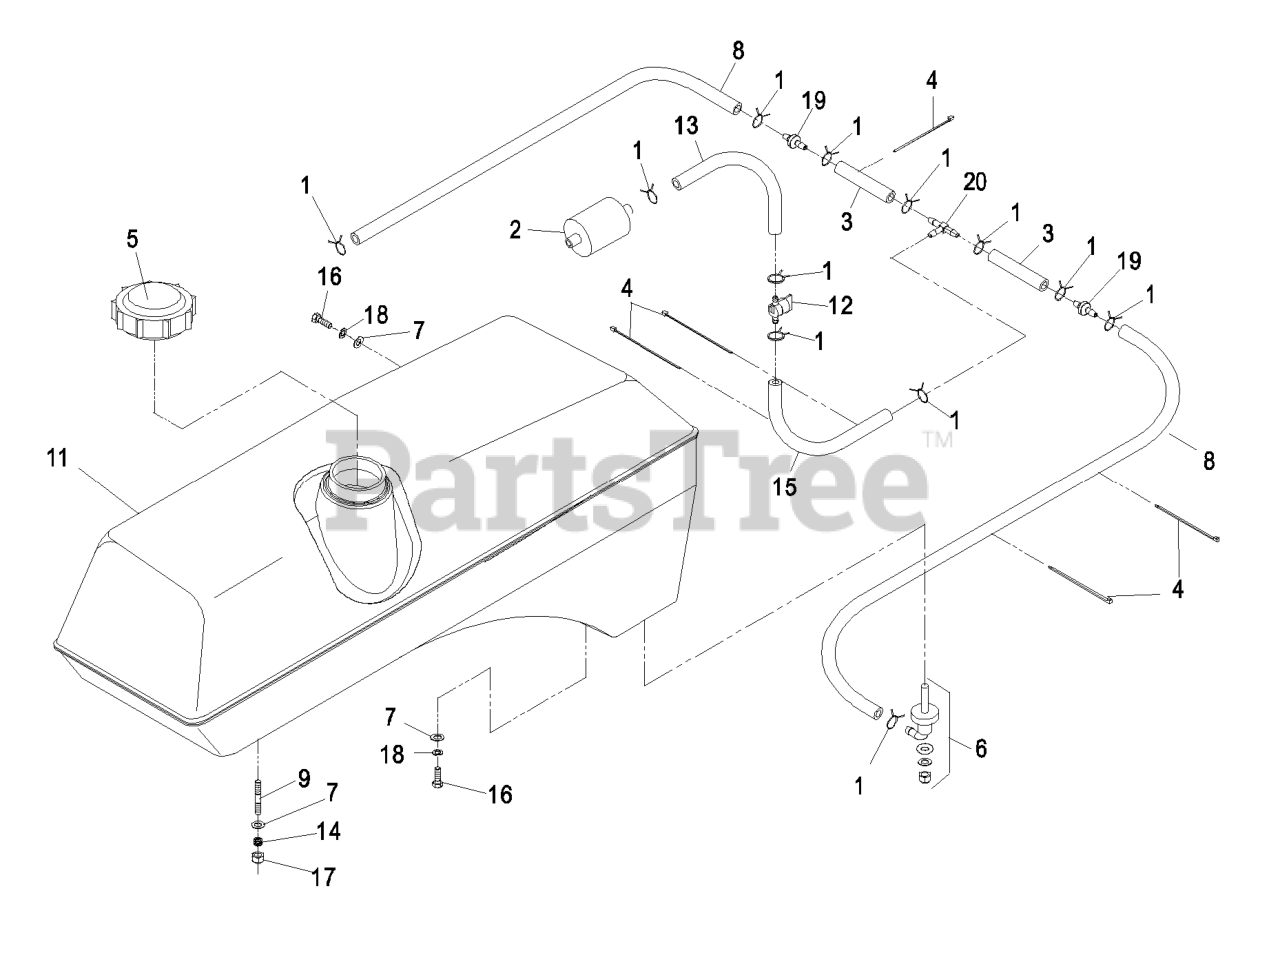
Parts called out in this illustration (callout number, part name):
2	Kohler Part No. 2405010 Fuel Filter
3	Hose, Fuel Line 2 1/2"
4	TIE-PLASTIC
5	CAP-FUEL, GAS
6	FITTING-FUEL, BULKHEAD
7	WASHER-PLAIN
8	HOSE-FUEL
9	STUD
12	VALVE-FUEL
13	HOSE-FUEL
14	SPRING-TANK, FUEL
15	HOSE-FUEL
16	SCREW-HH
17	NUT-LOCK, NI
18	WASHER-LOCK
19	VALVE-CHECK, FUEL
20	FITTING-TEE, BARBED
